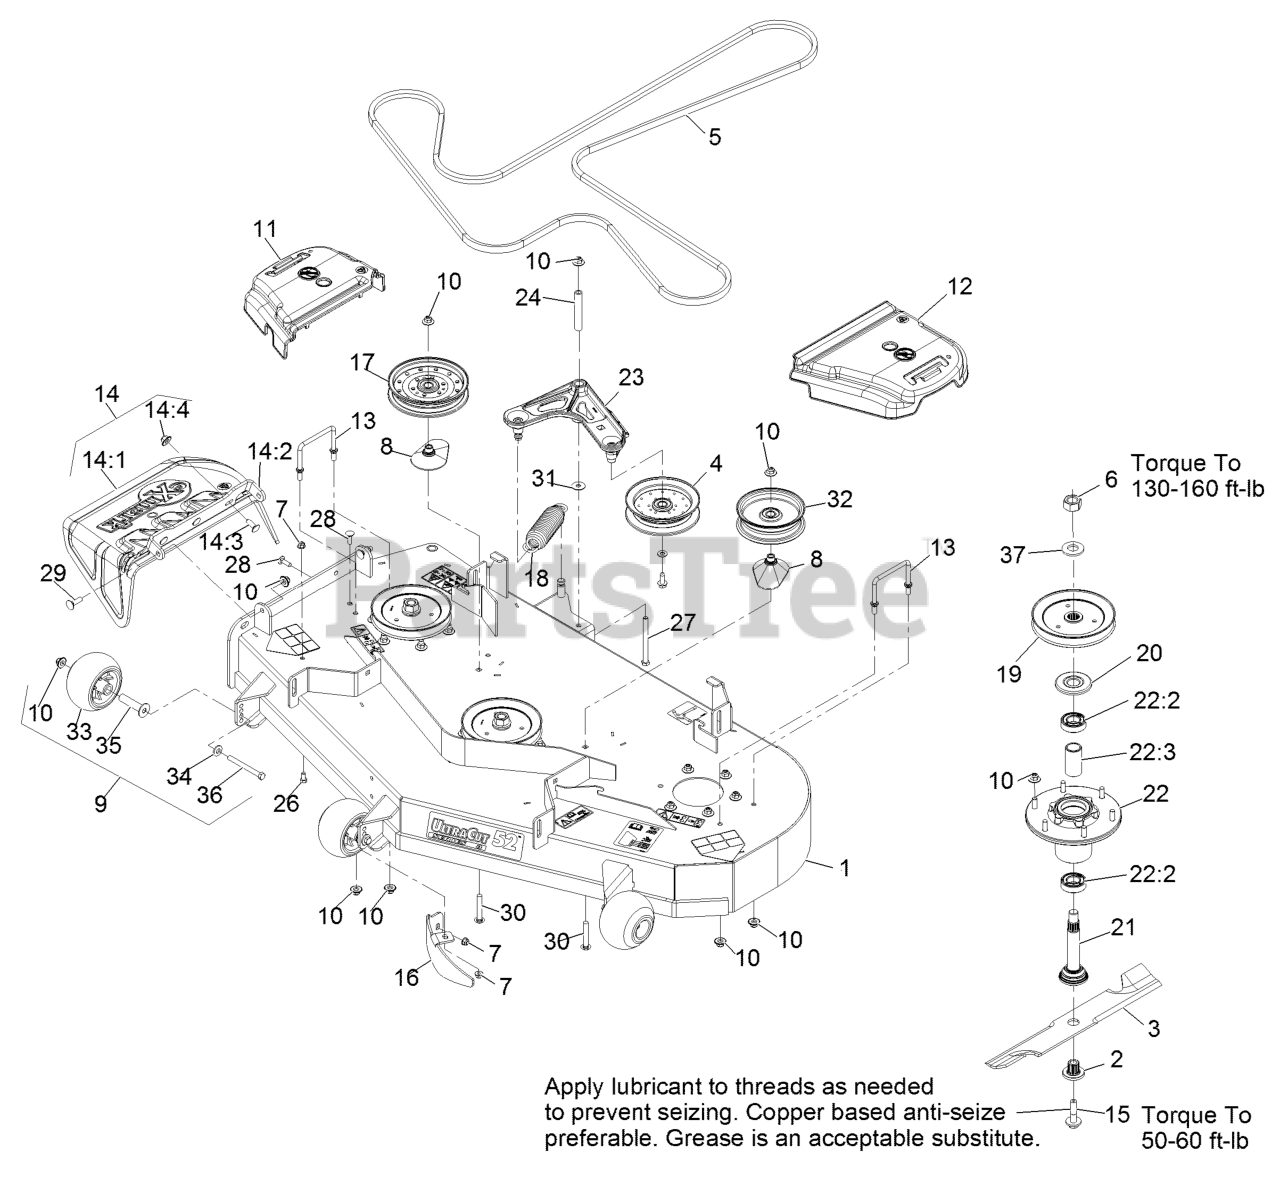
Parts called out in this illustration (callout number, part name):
1	ASM-DECK W/DECALS, 52
2	BUSHING,SPLINED
5	BELT-B162.50
6	NUT-HEX
7	NUT-HF, NI
8	SPACER-PULLEY
9	KIT, ANTI-SCALP ROLLER
10	Nut-Nyloc 3/8-16 Flg
11	COVER-BELT, RH
12	COVER-BELT, LH
13	WIREFORM-COVER
14	ASM,DISCHARGE CHUTE
14:1	CHUTE,DISCHARGE
14:2	BRACKET,DISCHARGE CHUTE
14:3	SCREW-CARR
14:4	Nut-Nyloc 3/8-16 Flg
15	SCREW,SEMS 1/2-20 X 2.19
16	BAFFLE-DOGLEG, LZE-PNS-52
18	SPRING-EXTENSION
19	SHEAVE,BLADE DRIVE 6.50
20	GUARD,BEARING TOP .989
21	ASM-SPINDLE AND SEAL
22	ASM-CUTTER HSG WITH BEARINGS
22:2	BEARING-BALL
22:3	SPACER-BEARING
23	IDLER ARM ASM
24	BUSHING
26	SCREW-HH
27	SCREW-HH
28	BOLT-CARR
29	BOLT-CARR
30	SCREW-CARR
32	IDLER-PULLEY, FLAT
33	ROLLER-SCALP, ANTI
34	WASHER-BELLEVILLE
35	AXLE, ROLLER
36	SCREW-HH 3/8-16 X 3 3/4 GR 8
